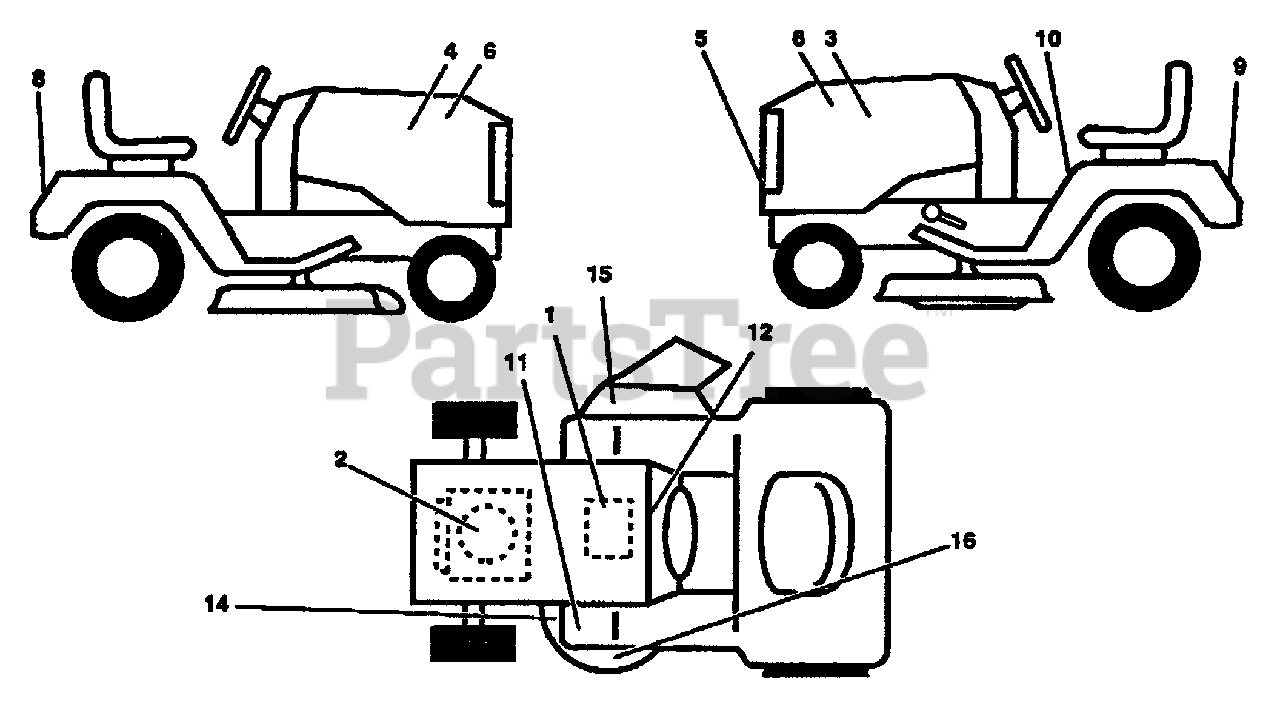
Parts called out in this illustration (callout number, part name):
1	Decal, Caution, Battery
2	Decal, HP, Engine
3	Decal, Hood, L.H.
4	Decal, Hood, R.H.
5	Decal, Logo, Grill
6	Decal, Model, Side Panel
8	Decal, Logo, Fender
9	Decal, USA
10	Decal, Operating, Warning, (English/French)
10	Decal, Operating, Warning, (Swedish/Danish)
10	Decal, Operating, Warning, (Norwegian/Finnish)
10	Decal, Operating, Warning, (German/Dutch)
10	Decal, Operating, Warning, (Spanish/Italian)
11	Decal, Clutch/Brake, (English/French/German/Dutch)
11	Decal, Clutch/Brake, (Swedish/Finnish/Danish/Norwegian)
11	Decal, Clutch/Brake, (Spanish/Italian)
12	Decal, Instruction, Operating, (English/French/German/Dutch)
14	Decal, Warning, Deflector, (Finnish/Swedish/Norwegian/Danish)
14	Decal, Warning, Deflector, (English/French/German/Dutch)
14	Decal, Warning, Deflector, (Spanish/Italian)
15	Decal, Warning, (Swedish/Finnish/Norwegian/Danish)
15	Decal, Warning, (English/French/German/Dutch)
15	Decal, Warning, (Spanish/Italian)
16	Decal, Rotating Blades, (Swedish/Finnish/Norwegian/Dannish)
16	Decal, Rotating Blades, (English/French/German/Dutch)
16	Decal, Rotating Blades, (Spanish/Italian)
